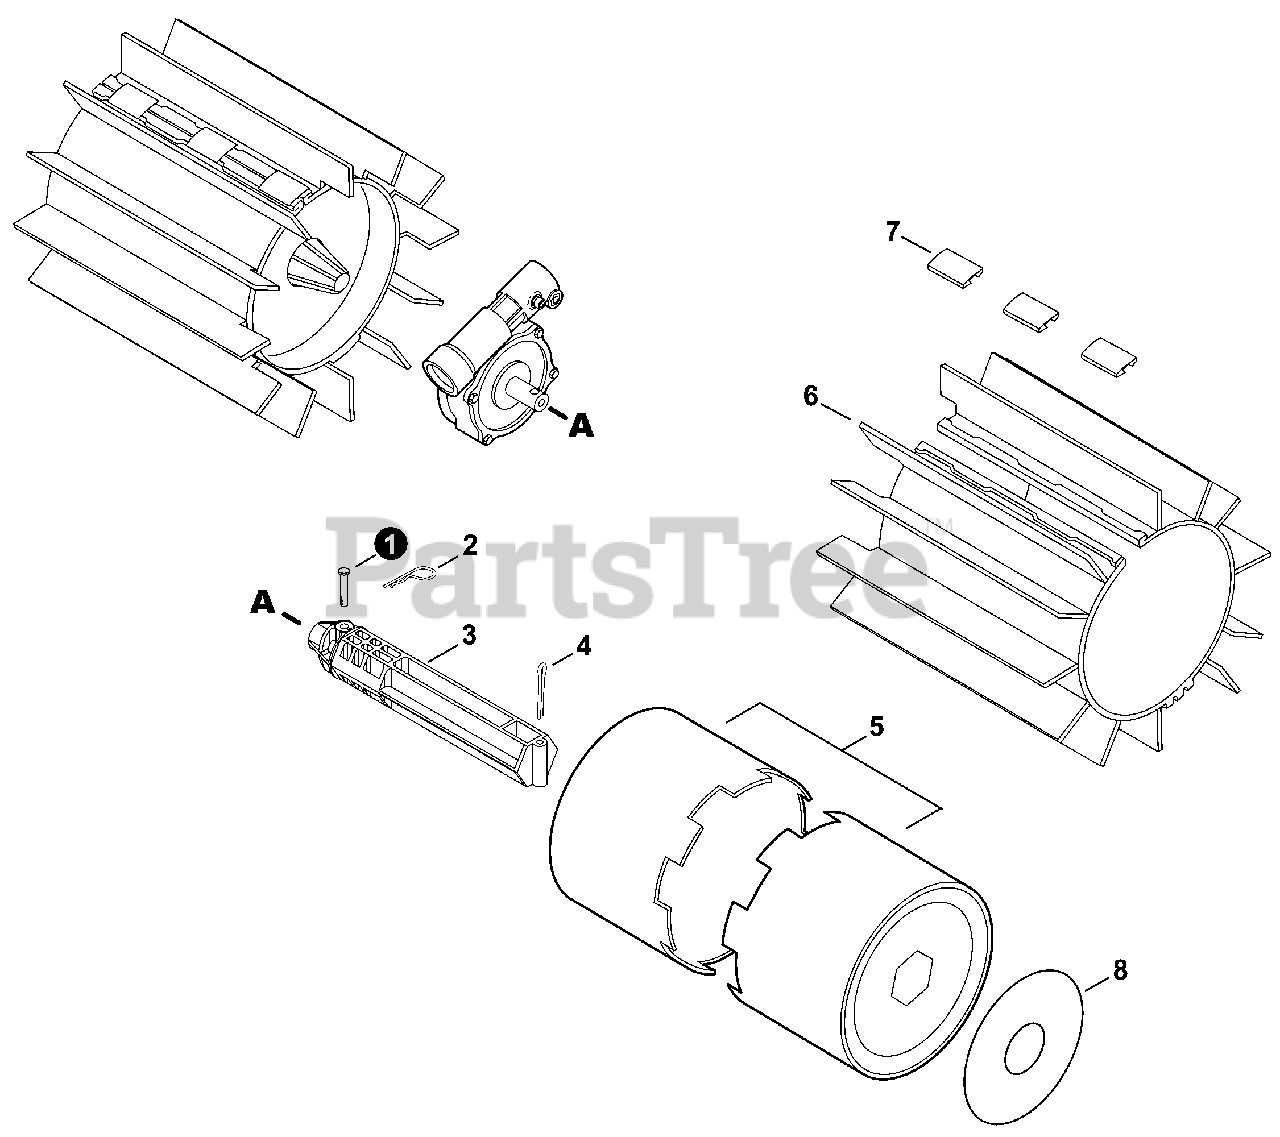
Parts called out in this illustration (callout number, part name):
1	PIN, CLEVIS
2	PIN, HITCH
3	AXLE, DRUM
4	PIN, COTTER
5	HUB, DRUM
6	BELT, SWEEPER
7	CLIP, BELT
8	LABEL, PROPADDLET
